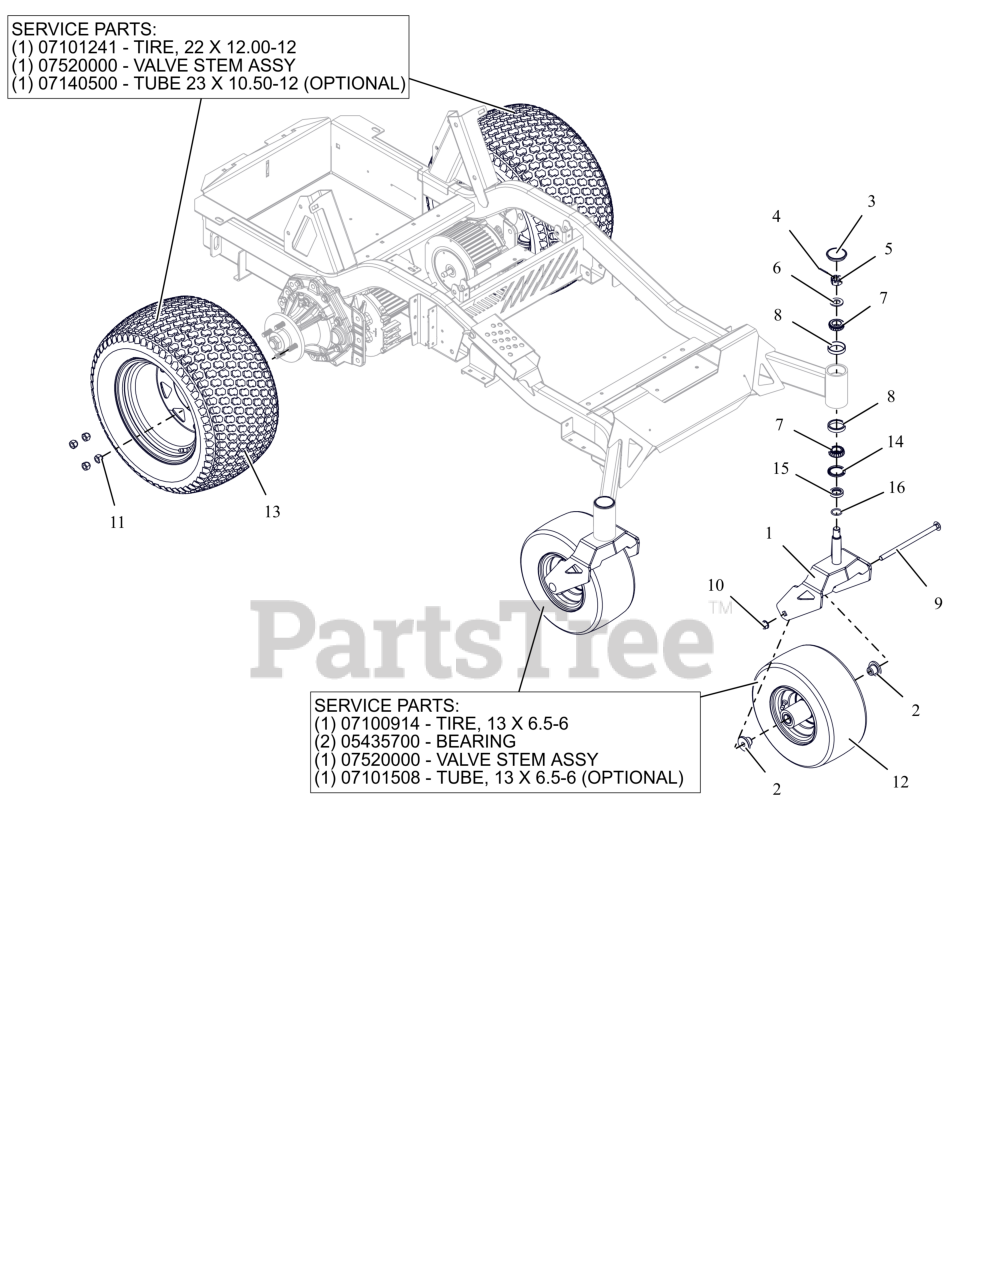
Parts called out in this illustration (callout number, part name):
1	WLDMT- CASTER FORK
2	SPACER, FRONT WHEEL
3	CAP, DUST
4	PIN,CTR.12X1.25EXTPRSQCT ZC120
5	NUT, SLOTTED .75-16
6	WSHR, FLT .812X1.469X.134 ZCC
7	BRG-CONE 1.0X.58
8	BRG-CUP1.980X.420
9	BLT-RHSN .50-13X9.00 G5 ZCC NS
10	NUT-LK-CTR-FLG .500-13 GG ZCC
11	NUT, WHEEL .50-20 ZCC
12	ASM, TIRE/WHEEL 13 X 6.50-6 BLK RIM
12	LAWN TIRE FRONT, 13X6.50-6 SMOOTH
12	BRG, 25MM ID X 52MM OD X 15MM
12	VALVE STEM ASS'Y
12	TIRE TUBE, 13/6.5-6 4 PLY TR87 90 BENT VALVE
13	ASM-WHL/TIRE 22X12-12 LG BLK
13	TIRE, 22X12.00-12
13	VALVE STEM ASS'Y
13	TIRE TUBE 22,23,24/8.50/9.50/10.00/10.50/12.00-12 4 PLY TR13 STRAIGHT VALVE
14	BEARING SEAL 1.5 X 2 X .18
15	SPCR, CASTER FORK (1.00)
16	O-RING 1.000X1.250X
